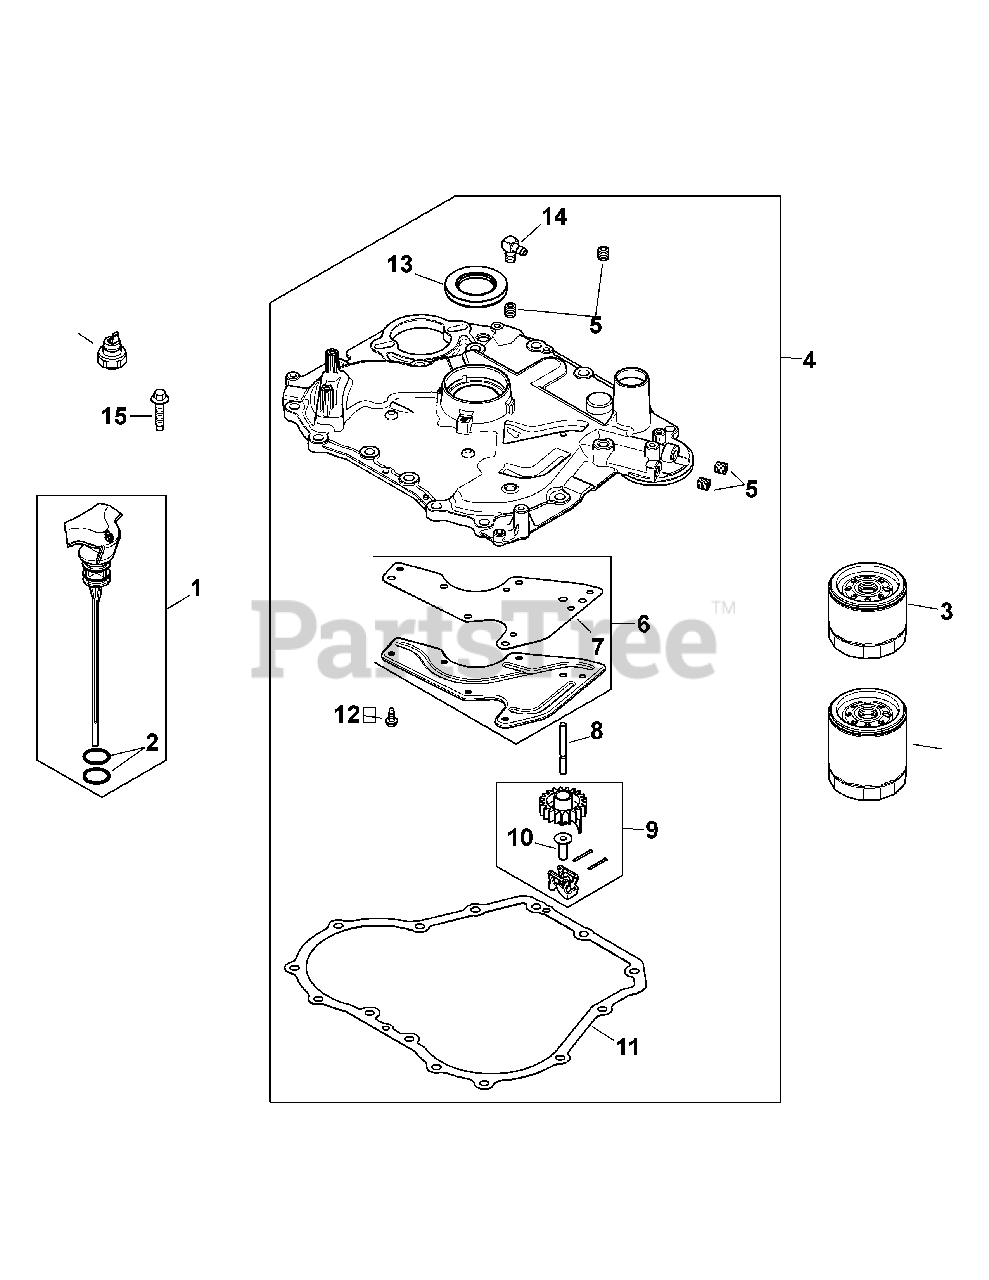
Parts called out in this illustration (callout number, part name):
1	Dipstick Assembly-Std Yellow
2	O-Ring
4	Closure Plate Assembly
5	Ctsk. Pipe Plug, 1/8
6	Oil Passage Cover Kit
7	Oil Passage Gasket
8	Governor Cross Shaft
9	Governor Gear Assembly
10	Governor Regulating Pin
11	Closure Plate Gasket
12	Flg. Thd. Frm. Screw, M5 X 0.8 X 13
13	Oil Seal
14	90° Hose Connector
15	Hex Flange Screw, 1/2
